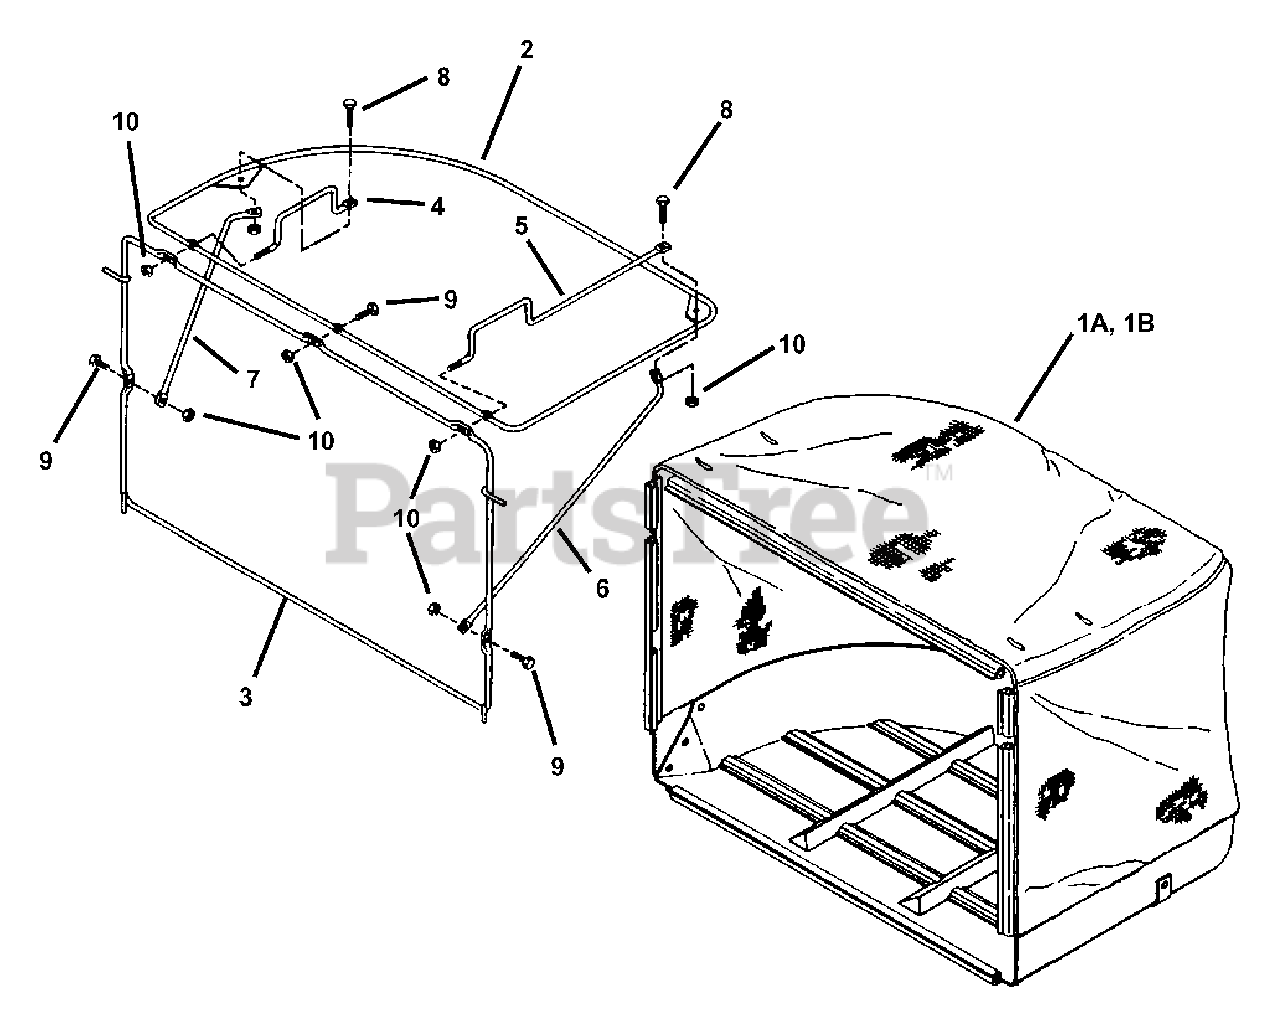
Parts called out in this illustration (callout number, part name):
1A	BAG, Cloth Grass
1B	BAG, Cloth Grass
2	WELDMENT, Top Frame
3	WELDMENT, Front Frame
4	HANDLE, Short
5	HANDLE, Long
6	BRACE, Large
7	BRACE, Small
8	SCREW, 1/4-20 x 1-1/4" Hex Head Cap
9	SCREW, 1/4-20 x 7/8" Hex Head Cap
10	NUT, 1/4-20 Hex Nyloc
